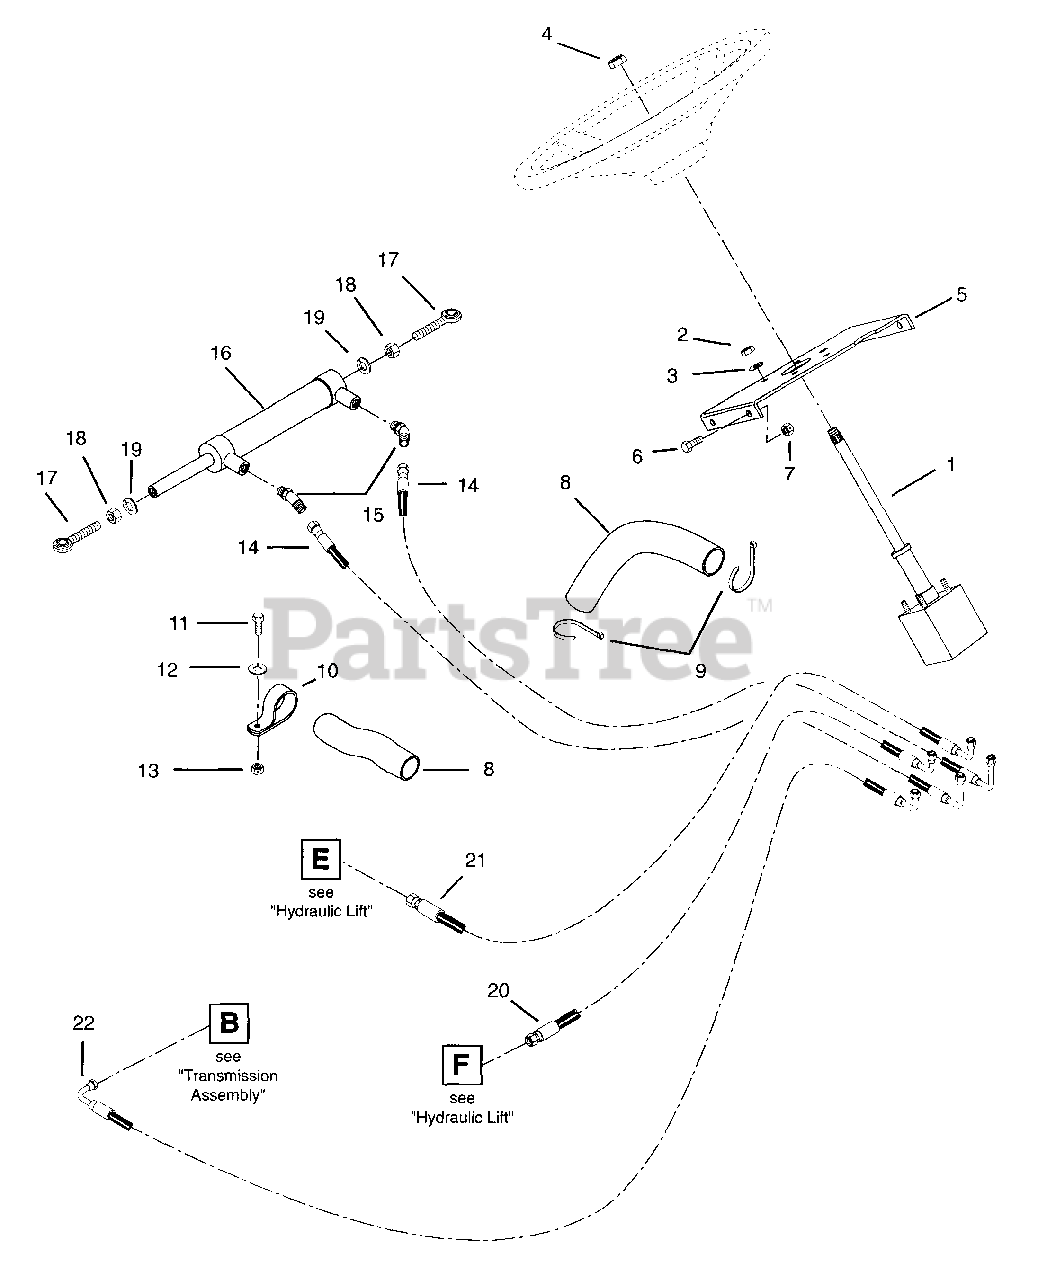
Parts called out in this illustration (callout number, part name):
1	Power Steering Unit
1	Kit - Power Steering Unit
2	Nut-Jam .31-24
3	Washer-Locking .31 x .078
4	Nut-Hex .62-11
5	Bracket-Steering Pump
6	Bolt-Hex .31-18 x .75 Grade 5
7	Nut-Locking-Center .31-18
8	Sleeve 12"
9	Tie Wrap, Black
10	Clamp, Nylon
11	Bolt-Hex .38-16 x .75 Grade 5
12	Washer-Flat-Steel .406 x .812 x .065
13	Nut-Locking-Center .38-16
14	Hydraulic Hose Assembly
16	Cylinder, Steering
17	Rod End, 1/2 RH
18	Nut-Hex .50-20 Grade 2
19	Washer-Locking .50 x .125
20	Assembly, Hydraulic Hose
21	Assembly, Hydraulic Hose
22	Assembly, Hydraulic Hose
